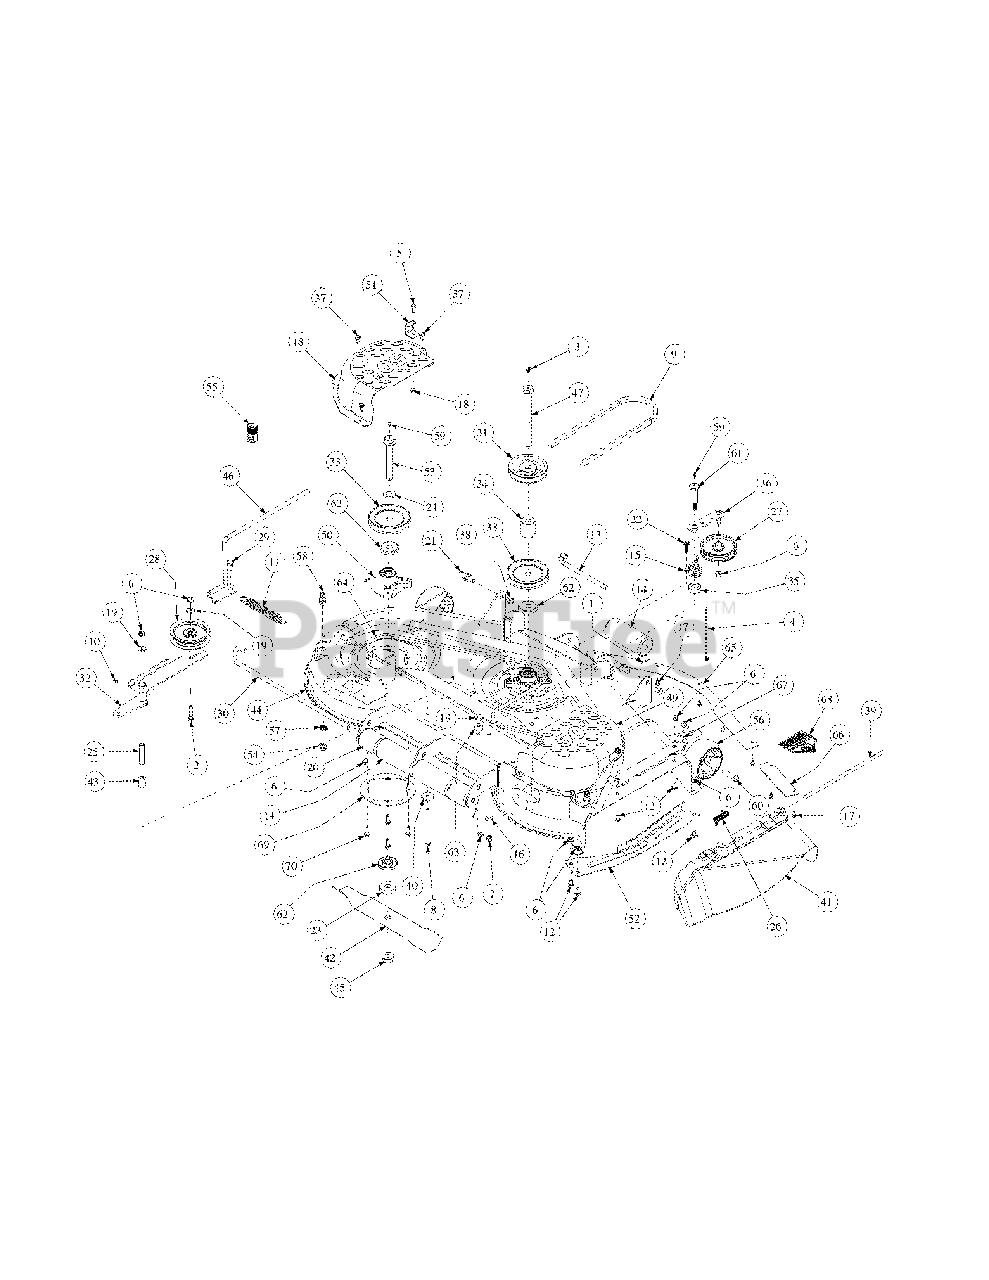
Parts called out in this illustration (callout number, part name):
1	Cotter Pin, .125 Dia x 1.0
2	Capscrew, 3/8-16 x 1-3/4
3	Grease Fitting, 1/4-28, 90°.
4	Cable Tie, 3/16 x .05 x 7.4
5	Hex Cap Screw, 5/16-18 x 3/4
6	Hex Nut Flange lock, 3/8-16
7	Nut 7/16-14, Nylock
8	Hex Cap Screw, 3/8-16 x 5.00
9	V-Belt, B-Section
10	Grease Fitting, 1/4-28 x 3/16
11	Extension Spring, 1.0 OD x 5.00
12	Carriage Bolt, 3/8-16 x .75 Lg
13	Roller Pin, 1/2 Dia x 7.31 Lg
14	Front and Rear Roller
15	Torsion Idler Spring
16	Flat Washer, .469 ID x .875 OD x .105
17	Screw, TT, 1/4-20 x .5, Hex Index Washer
18	Hex Flange Lock Nut, 5/16-18
19	Flat Washer, .406 ID x 1.0 OD x .105
20	Short Roller
21	Pin, 5/8 Dia x 1.2 Lg
22	Carriage Screw, 3/8-16 x 1.25
23	Spacer, .76 ID x 2.00 OD x .477
24	Spacer, .812 ID x .218 Lg.
25	Spacer, .39 ID x .625 OD x 2.75
26	Torsion Spring
27	Flat Pulley with Flanges
28	Idler Pulley, 4.06 OD with Deep Flange
29	Shoulder Screw, .50 x .27 Lg; 3/8-16
30	Roller Pin Rod
31	V-Pulley, 4.75 OD
32	Idler Arm Assembly, Flat Top Bearing
33	Pulley, A Sect x 4.90
34	Spacer, .760 ID x 1.75 OD x 1.969
35	Spacer .760 ID x 1.5 OD
36	Idler Arm Assembly
37	Self Tapping Screw 5/16-18 x .750
38	Hex Nut, 1/2-13, Insert Lock
39	Hinge Pin, .375 x 14.06
40	Flat Washer, .390 x 1.5 x .134
41	Chute Deflector
42	Hi-Lift Blade, 17.9
43	Spacer, .39 ID x .875 OD x 1.00
44	Deck Assembly 50"
45	Flange Hex Nut, 3/4-16
46	Spring Tension Rod Assembly
47	Hex Cap Screw, 3/4-16 x 8.00
48	Left Hand Belt Cover
49	Right Hand Belt Cover
50	Blade Spindle Assembly
51	Tension Rod Stop Bracket
52	Finger Guard
53	Spindle Bolt 3/4-16 x 5.37
54	Hex Nut, M16-1.5
55	Adaptor, Water Nozzle
56	Deck Wheel, 5.00 Dia.
57	Lock Washer, 17 x 23.8 x 1.9
58	Nozzle, Deck Water
59	Grease Fitting
60	Shoulder Screw .498 x 1.53
61	Shoulder Screw .68 x 2.11
62	Spindle Spacer
63	Spacer .406 ID x 1.00 OD x 0.38
64	V-Belt, 1/2 x 91 LG
65	Skirt, Center, 50"
66	Skirt, Right Hand, 50"
67	Chute Mounting Bracket
68	Decal, Danger Hands & Feet
69	Spindle Plate
70	Self Tapping Screw 5/16-18 x 1.00
